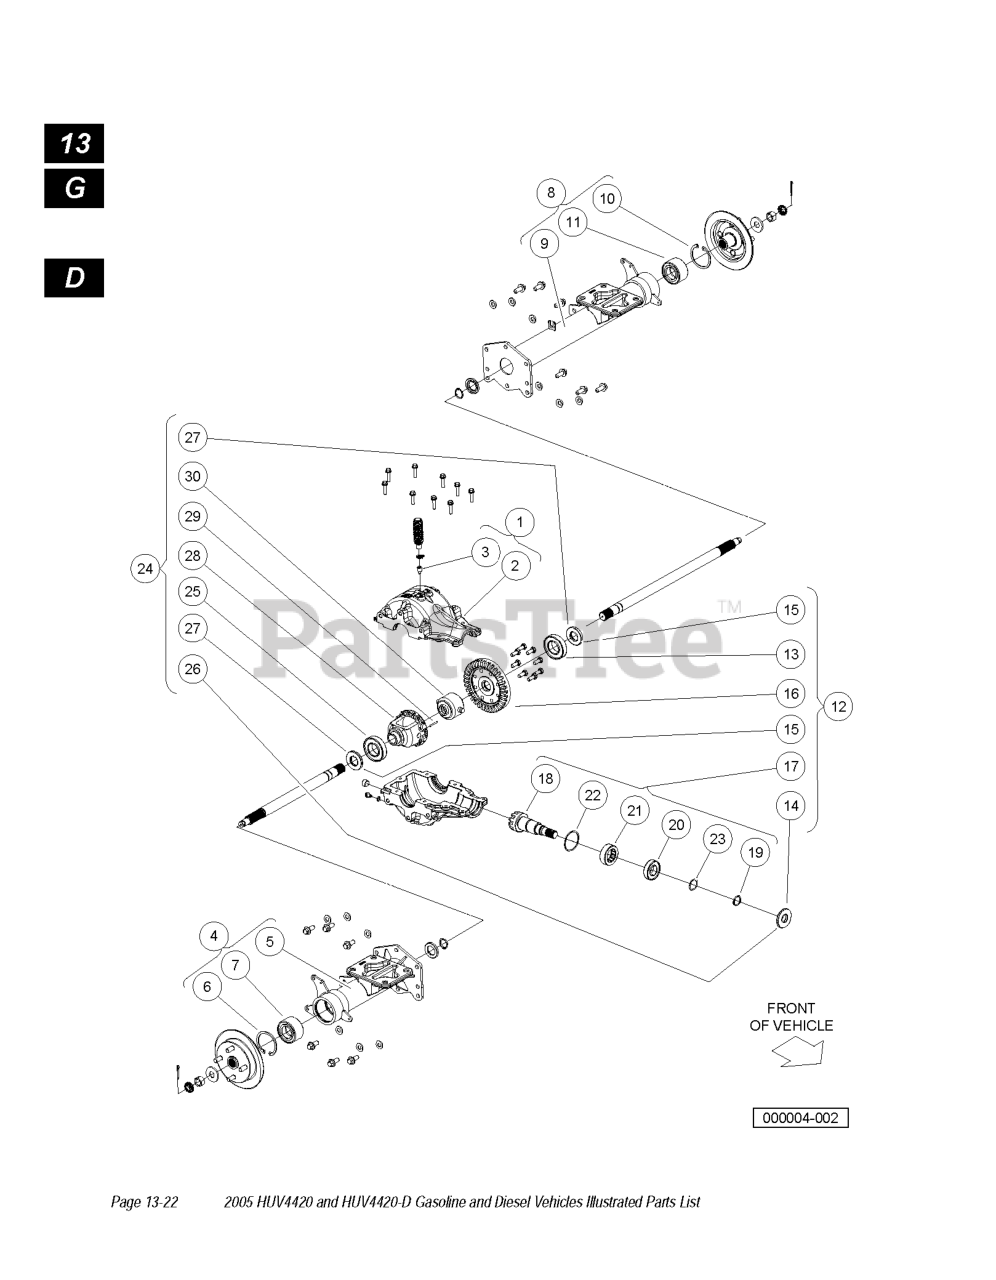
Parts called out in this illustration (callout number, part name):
1	ASM-GEARCASE-UPPER
3	VENT, TOP, UPPER HOUSING
4	ASM-AXLE TUBE
6	RING, RETAINING, INTERNAL
7	BEARING, DAC
8	ASM-AXLE TUBE LH
10	RING, RETAINING, INTERNAL
11	BEARING, DAC
12	KIT-REAR AXLE GEAR REPAIR
13	BEARING, BALL, 6208 C3
14	SEAL, DUAL LIP 25X 62X 7TC
15	SEAL, DUAL LIP 30X 62X 8TC
19	RING, RETAINING EXTERNAL
20	BEARING, BALL 6206R
21	BEARING, NEEDLE, DRAWN SHELL
22	WASHER, 2.625 X 2.367 X .06
23	SHIM, 1.50 X 1.189 X .008
24	ASM-DIFFERENTIAL & CARRIER
25	BEARING, BALL, 6208 C3
26	SEAL, DUAL LIP 25X 62X 7TC
27	SEAL, DUAL LIP 30X 62X 8TC
28	HOUSING, DIFFERENTIAL, MACH
29	PIN, DOWEL, 4 X 35
30	ASM, LOCKER, NONGREASE/SPACERS
